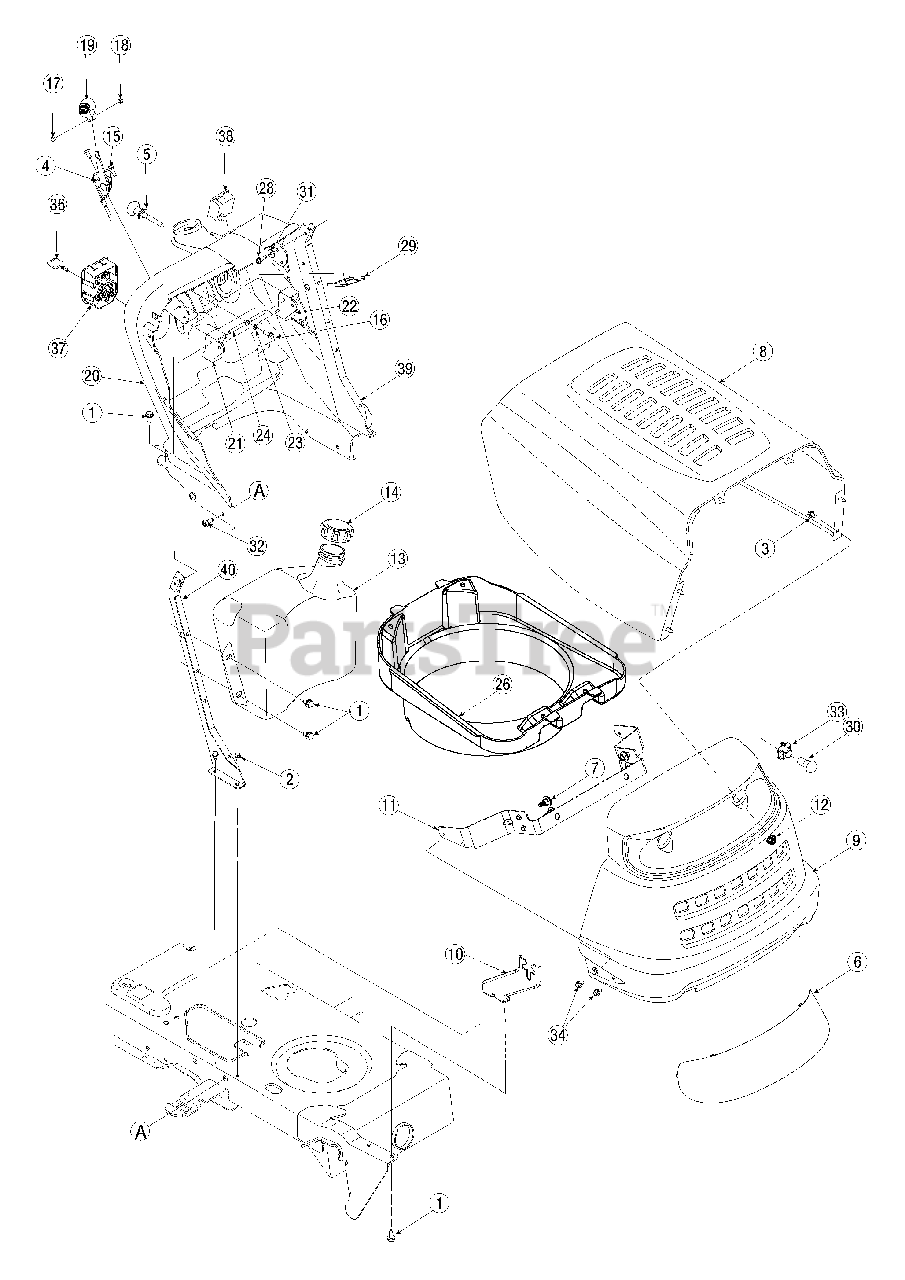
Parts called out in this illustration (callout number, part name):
1	Screw, 5/16-12 x.750
2	Self-tapping Screw, 1/4-20 x.5
3	Hex Cap Screw, 1/4-20 x.62
4	Throttle/Choke Cable
5	Choke Knob/Cable
6	Headlight Lens
7	Shoulder Screw,.43 x.29
13	Fuel Tank, Two Gallon
14	Fuel Cap
15	Screw, 1/4-14 x.625
16	Self-tapping Screw, 1/4-15 x.75
17	Truss Phillips Screw, #8-32 x.375
18	Hex Nut, #8-32
19	Throttle Control Knob
20	Dash Panel
21	Cruise Control Button
22	Parking Brake Button
23	Flat Washer, 9/32 x 1/2 x 1/16
24	Brake/Cruise Pivot Rod
26	Hood Plenum
27	Electric PTO Switch
28	Self-tapping Screw, 1/4-20 x.75
29	Switch Brkt., Electric PTO
30	Lamp
31	Bell Washer,.265 x.75 x.062
32	Screw, 5/16-18 x.75
33	Headlight Socket
34	Hex Index Screw, 1/4-20 x.625
35	Choke Plug
36	Ignition Key w/ plastic cover
37	Ignition Switch
38	Systems Ind. Monitor w/ Hour Meter
